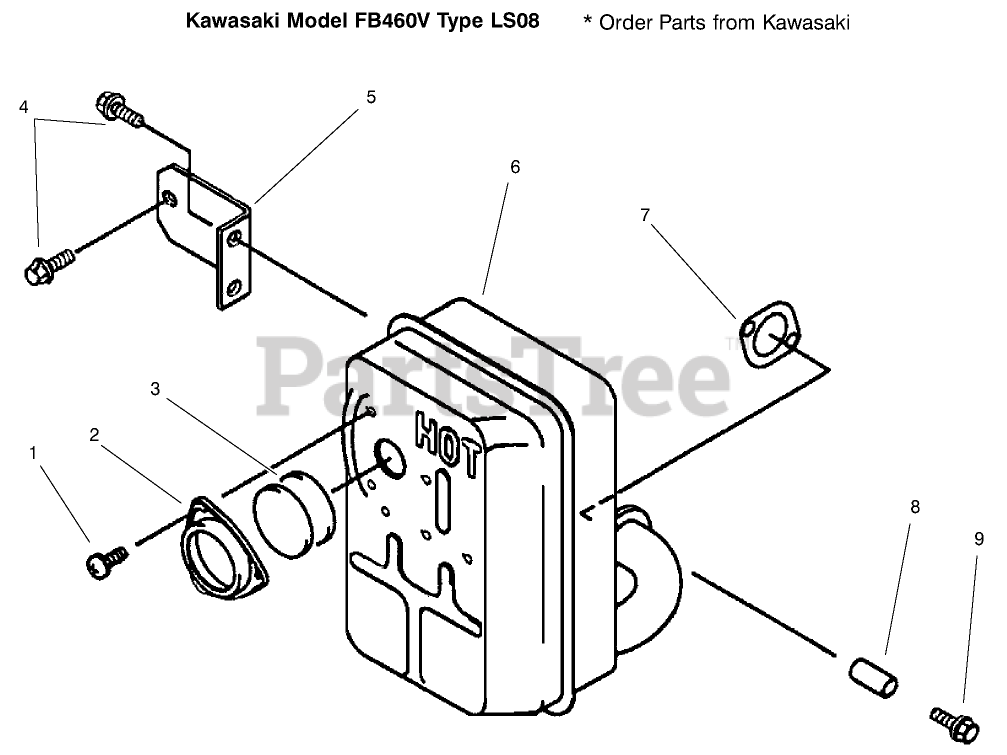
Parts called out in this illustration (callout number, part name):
1	Screw
2	Cap
3	Arrestor-Spark
4	Bolt-Flange
5	Bracket
6	Muffler ASM
7	Gasket-Muffler
8	Collar
9	Bolt-Flanged (8X45)
